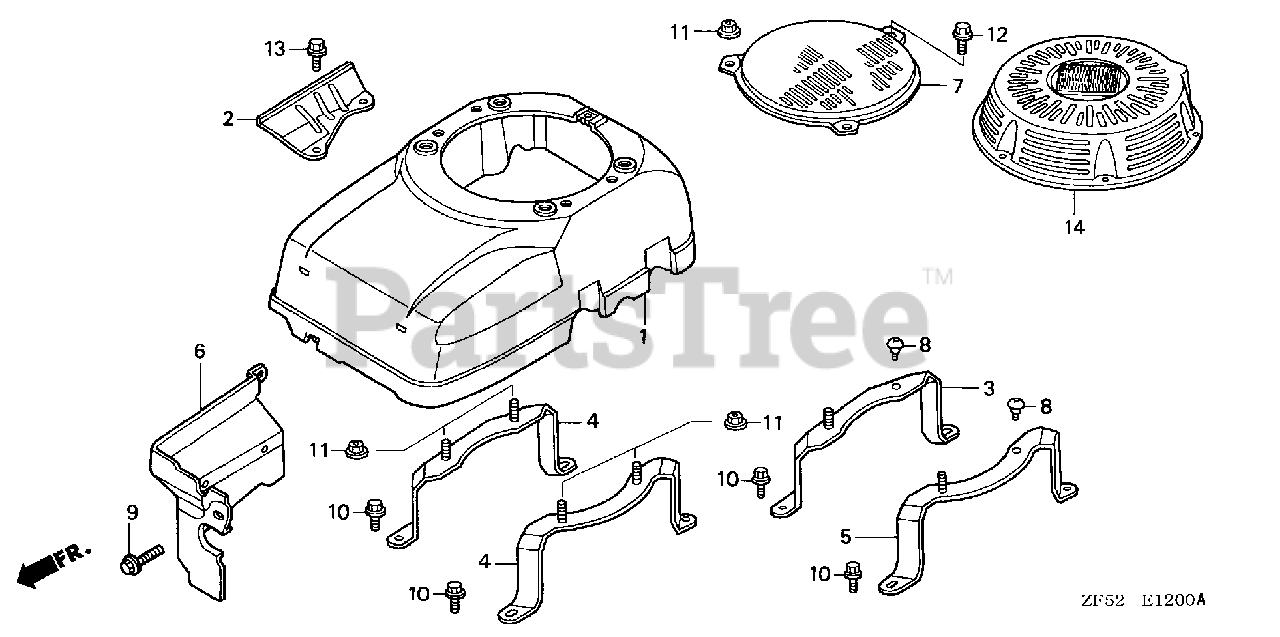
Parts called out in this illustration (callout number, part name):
1	COVER, FAN *R8* (BRIGHT RED)
1	COVER, FAN *R280* (POWER RED)
2	PLATE, SIDE
4	BRACKET, FAN COVER
10	BOLT, FLANGE (6X16) (CT200)
11	NUT, FLANGE (6MM)
13	BOLT, FLANGE (8X20)
